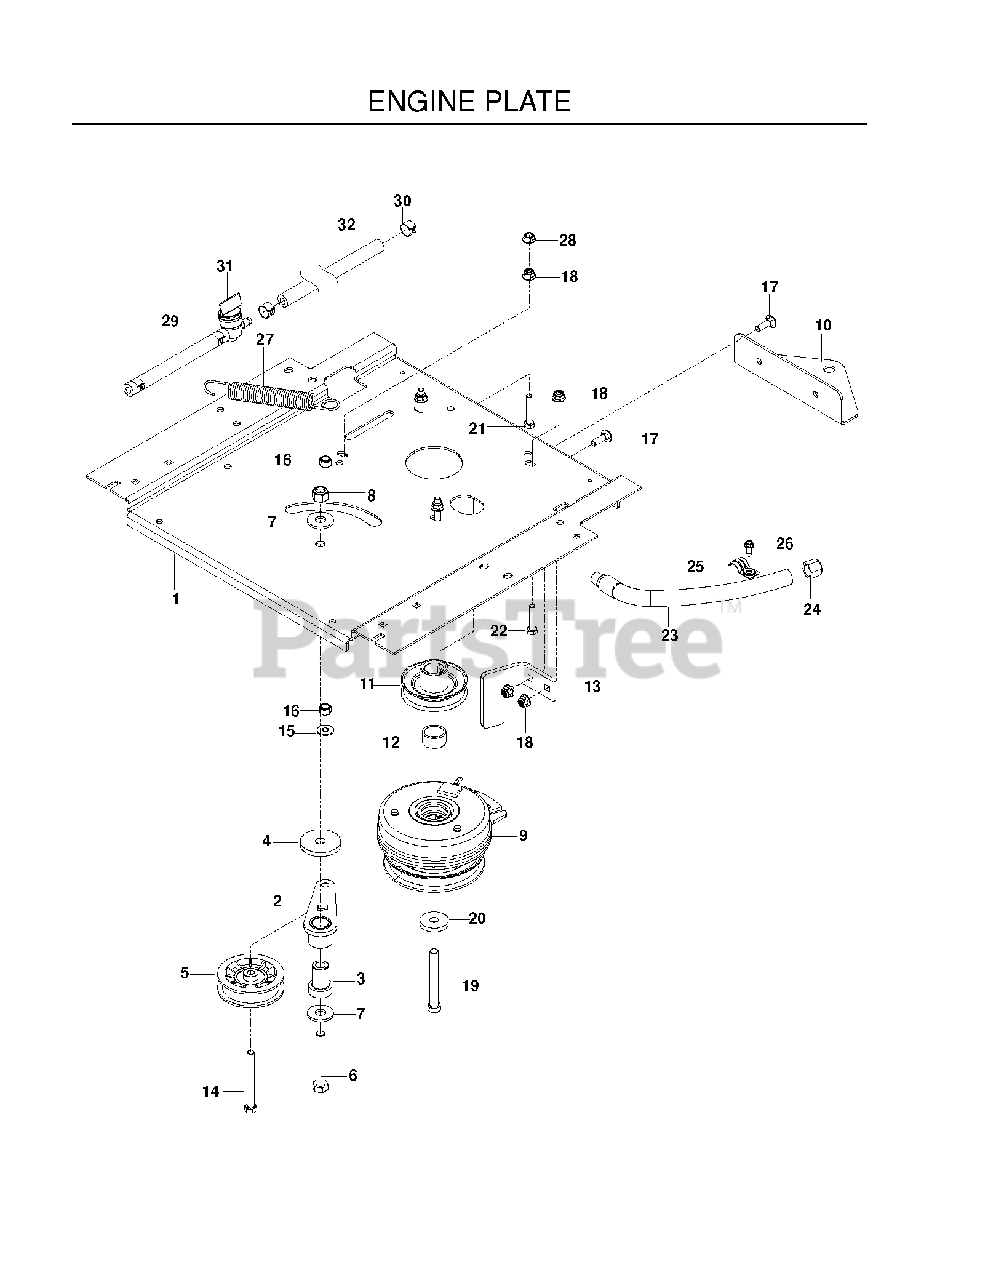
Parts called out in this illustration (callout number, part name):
1	PLATE, ENGINE BLK
2	IDLER ARM WELDMENT
3	IDLER SPINDLE
4	HEAVY WASHER
5	PULLEY, IDLER
6	HCS 1/2C X 3 1/4
7	WASH USS FLAT 1/2
8	NUT 1/2-13 HEX NYLOC ZD
9	CLUTCH, 105 FT-LBS
10	HITCH, BLACK
11	PULLEY, ENGINE
12	T & B SPACER
13	STOP, CLUTCH, BLACK
14	HCS 3/8-16X3 1/2 GR5
15	WASHER 5/16 FLAT
16	NUT 3/8-16 NYLOC
17	RHSNB 5/16C X 1
18	5/16-18 NYLOC FLANGE NUT
19	HCS 7/16-20X3-1/2 GR 5 ZN
20	CLUTCH, WASHER
21	HCS 5/16C X 1 3/4
22	CAPSCREW 5/16 X 1/1/2 HEX HEAD
23	OIL DRAIN HOSE
24	DRAIN CAP
26	SCREW 1/4 X 5/8
27	SPRING, DECK DRIVE
28	NUT 5/16C WHIZ
29	FUEL LINE 2.5"
30	HOSE CLAMP
31	FUEL VALVE
32	GAS LINE 10"
